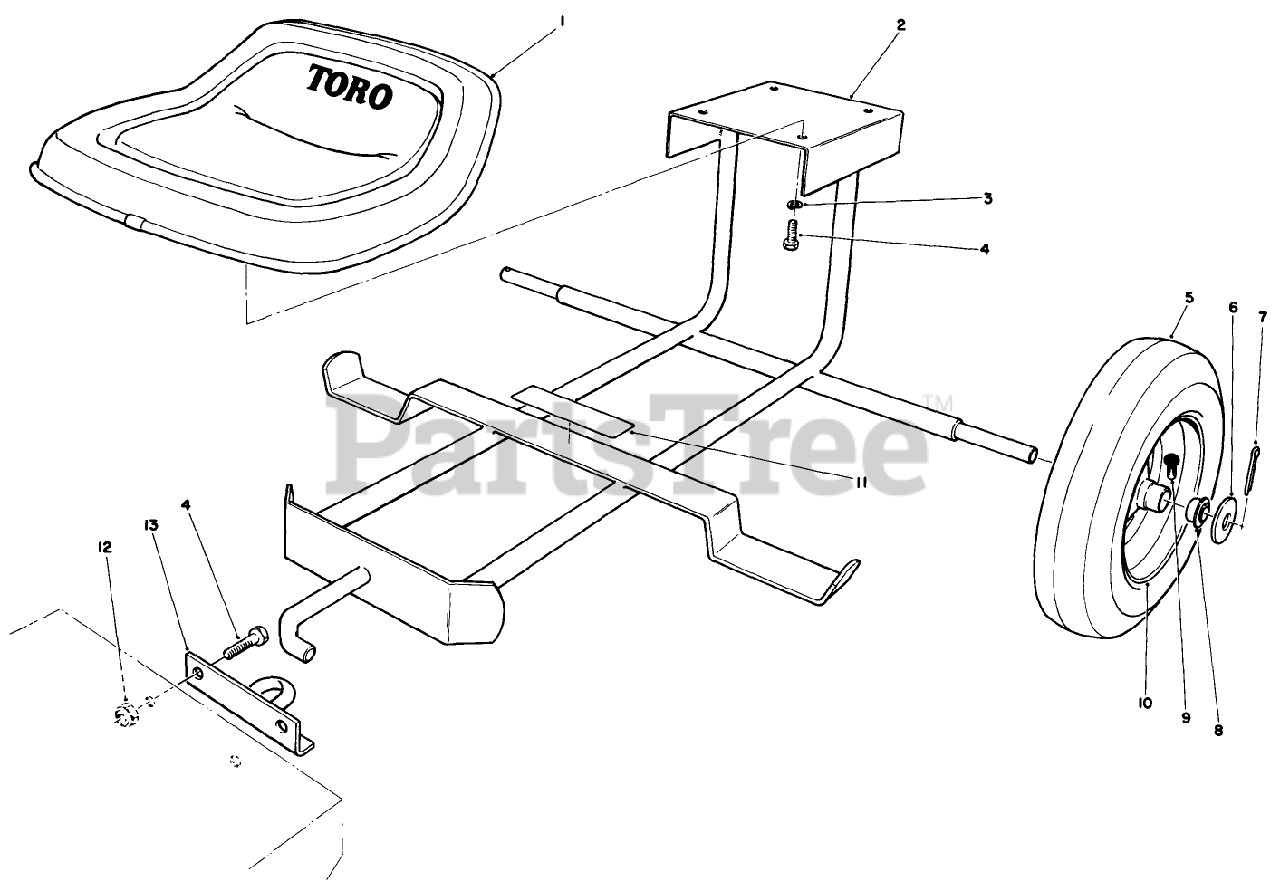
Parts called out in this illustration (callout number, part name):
3	WASHER-LOCK
4	SCREW-HH
6	WASHER-FLAT
7	PIN-COTTER
9	INNER TUBE VALVE STEM
12	NUT-LOCK, NI
13	HITCH WA *R
